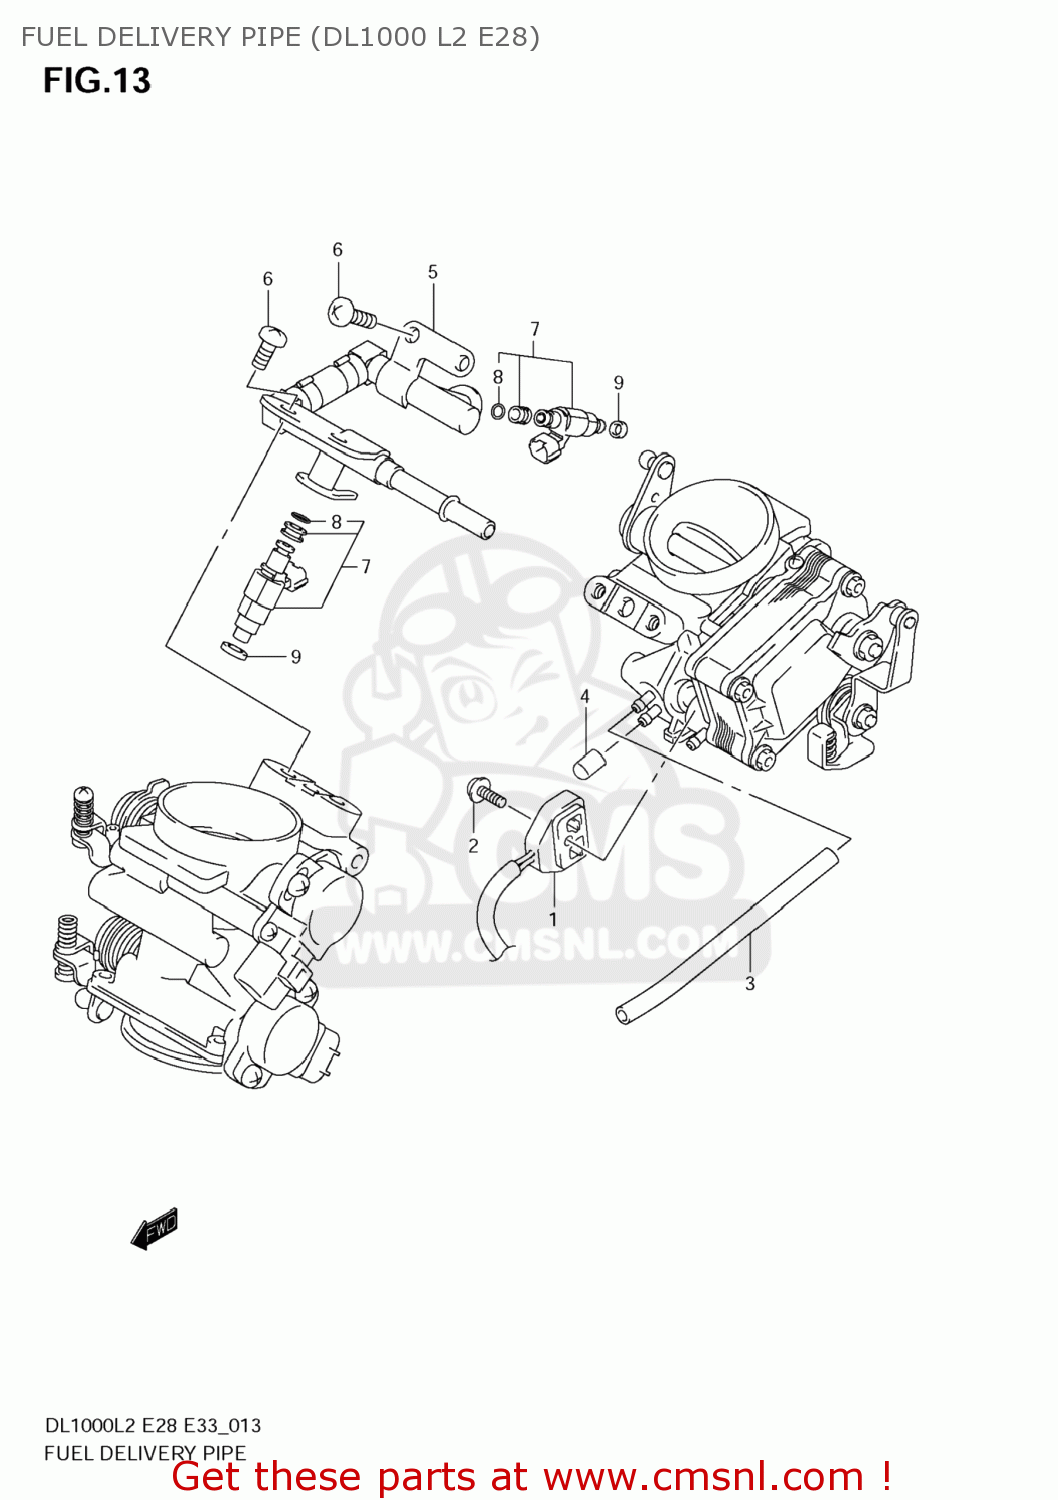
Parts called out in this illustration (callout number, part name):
1	HARNESS ASSY
2	SCREW
3	HOSE(L:425)
4	CAP
5	DELIVERY PIPE ASSY
6	SCREW
7	INJECTOR ASSY
8	O-RING
9	CUSHION,FUEL INJECTOR
